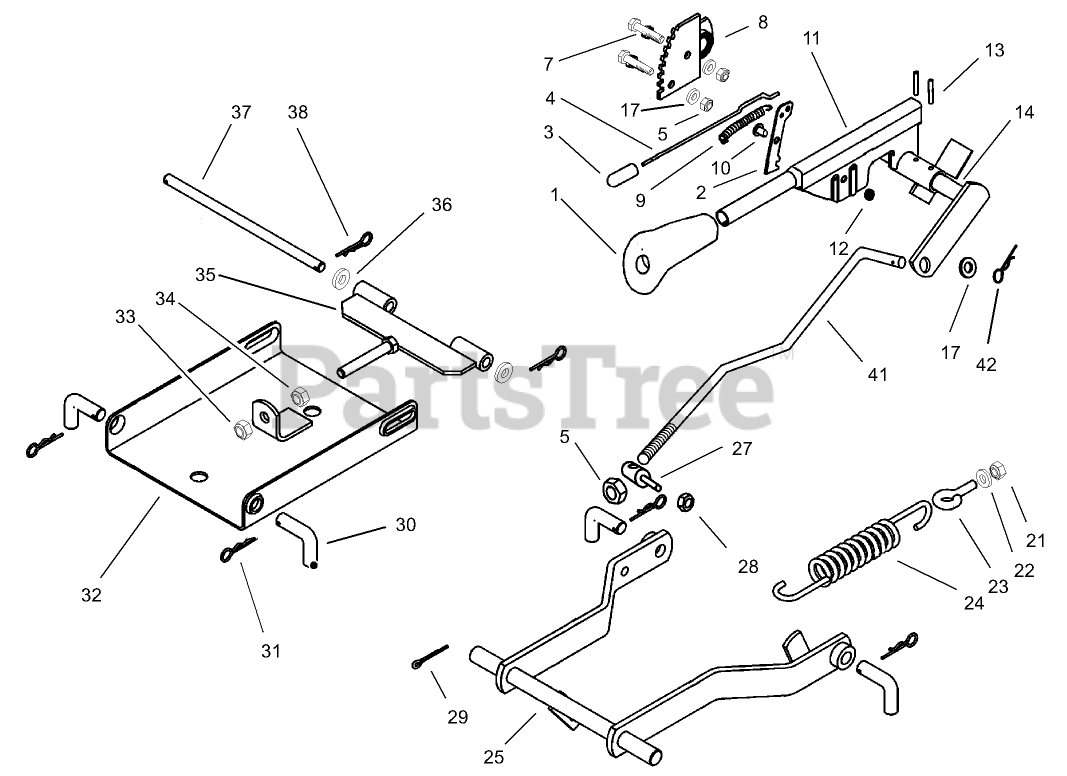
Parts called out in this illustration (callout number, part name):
1	GRIP-HANDLE
2	RATCHET-PLATE, PIVOT
3	BUTTON-PLUNGER
4	ROD-CONNECTION
5	NUT-LOCK, NI
7	SCREW-HH
8	SEGMENT-GEAR
9	SPRING
10	PIN-LEVER, ARM
11	LEVER-ARM, HEIGHT ADJ.
12	CLIP-PIN
13	PIN-SPRING
14	SHAFT-HEIGHT ADJ.
17	WASHER-PLAIN
21	NUT-LOCK, NI
22	WASHER-FLAT
23	BOLT-EYE
24	SPRING-LIFT
25	PIVOT ARM ASM
27	PIN-LIFTING
28	NUT-LOCK, NI
29	PIN-COTTER
30	PIN-BENT
31	PIN-HAIR
32	SUSPENSION-MOWER DECK, FRONT
33	NUT-HEX
34	NUT-HEX
35	HOLDER-FRONT
36	WASHER-FLAT
38	PIN-HAIR
41	ROD-HEIGHT, ADJ.
42	PIN-COTTER
